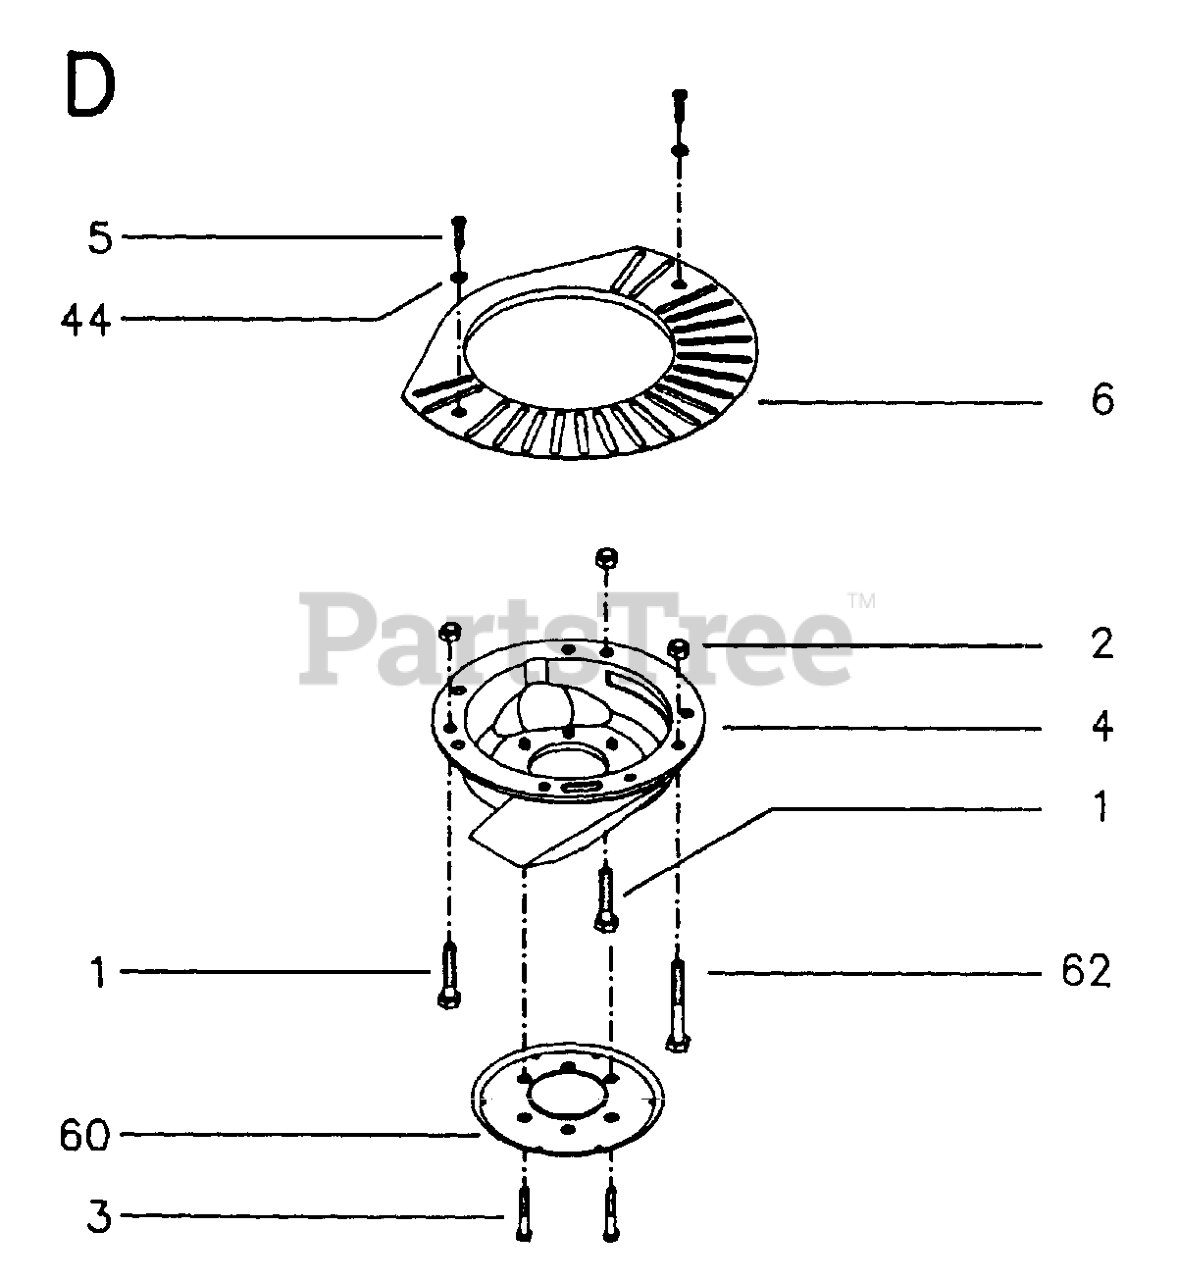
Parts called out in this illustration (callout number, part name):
2	LOCKNUT M8
4	REPL BY 516 69 84-11
6	CENTER PLATE
44	WASHER
